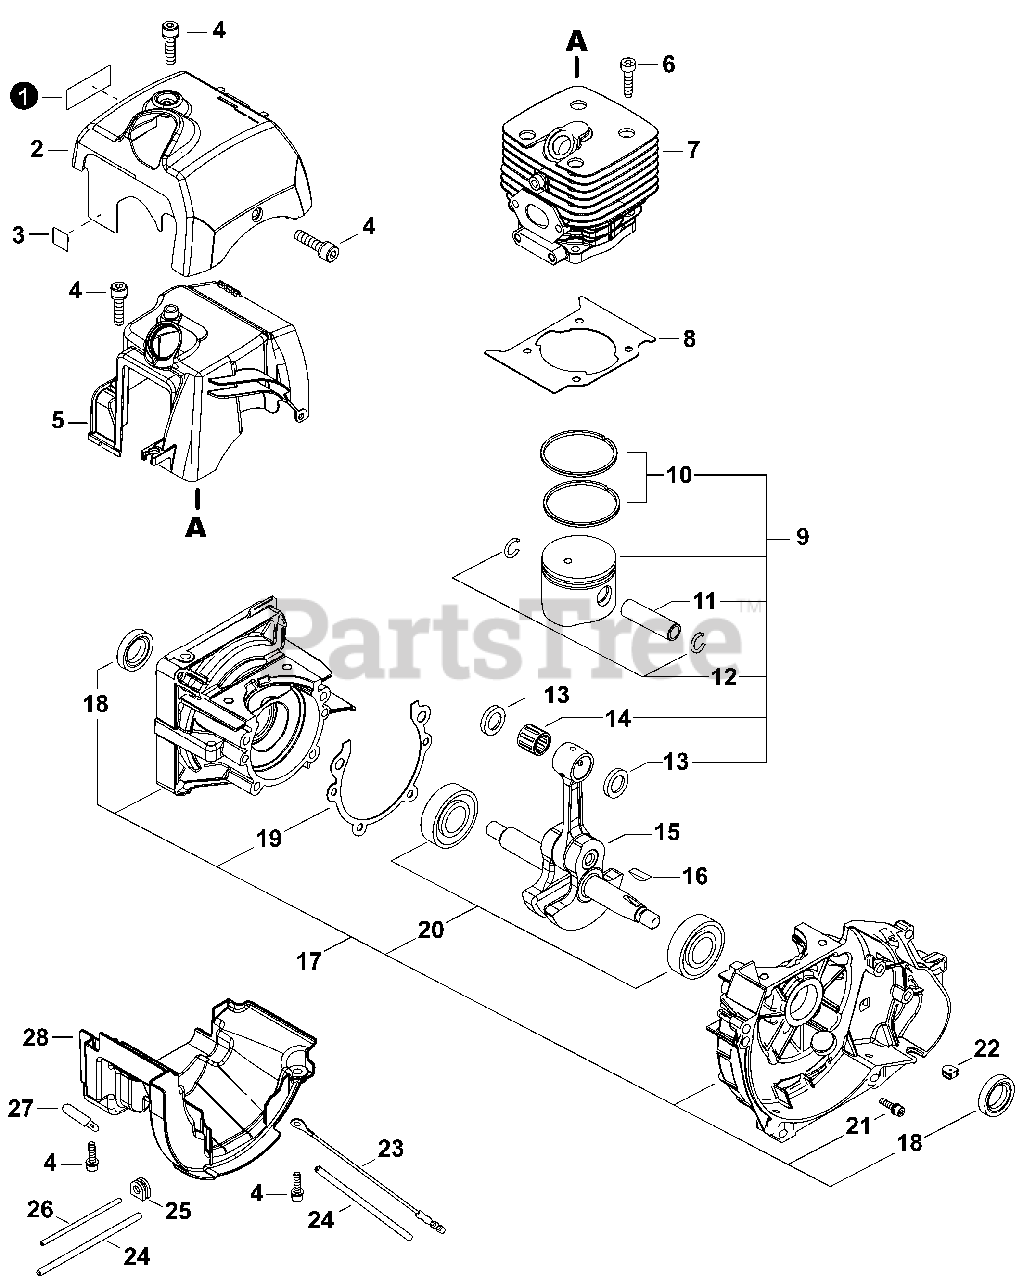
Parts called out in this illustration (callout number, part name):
1	LABEL - MODEL SRM-520ES
2	COVER, ENGINE
3	LABEL - PURGE PUMP
4	BOLT, TORX 5x16
5	COVER, CYLINDER
6	BOLT, TORX 5x20
7	CYLINDER
8	GASKET, CYLINDER
9	PISTON KIT
10	RING, PISTON
11	PIN, PISTON
12	RING, SNAP
13	WASHER, THRUST 11
14	BEARING, NEEDLE 11
15	CRANKSHAFT ASSY
16	KEY, WOODRUFF
17	CRANKCASE SET
18	SEAL, OIL
19	GASKET, CRANKCASE
20	BEARING, BALL 6202
21	BOLT, TORX 5x30
24	TUBE, INSULATOR 8x9x125
26	PIPE 3x6x160
28	PLATE, INSULATOR
